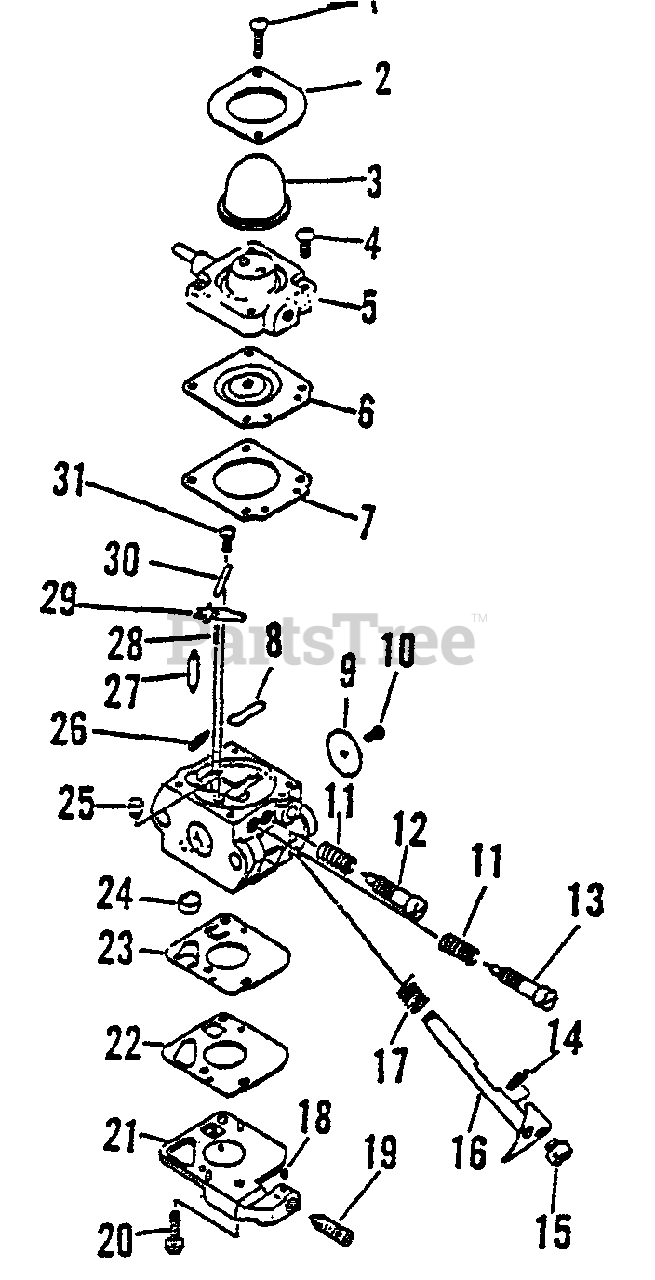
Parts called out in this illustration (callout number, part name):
1	SCREW, RETAINER
2	RETAINER, PURGE BULB
3	BULB, PURGE
4	SCREW, PURGE BASE
5	BASE, PURGE
6	DIAPHRAGM
7	GASKET, METERING
8	PLUG, WELCH
9	VALVE, THROTTLE
12	NEEDLE - LOW SPEED
13	NEEDLE - HIGH SPEED
14	RING, RETAINING
16	SHAFT, THROTTLE
17	SPRING, RETURN
18	PIECE, FRICTION
19	SCREW, IDLE ADJUST
20	SCREW, PUMP COVER
21	BASE, PURGE
22	GASKET, PURGE
23	DIAPHRAGM, PURGE
24	STRAINER
25	NOZZLE, CHECK VALVE
26	RING, RETAINING
27	VALVE, NEEDLE
28	SPRING
29	LEVER, METERING
30	PIN
31	SCREW, METERING LEVER PIN
